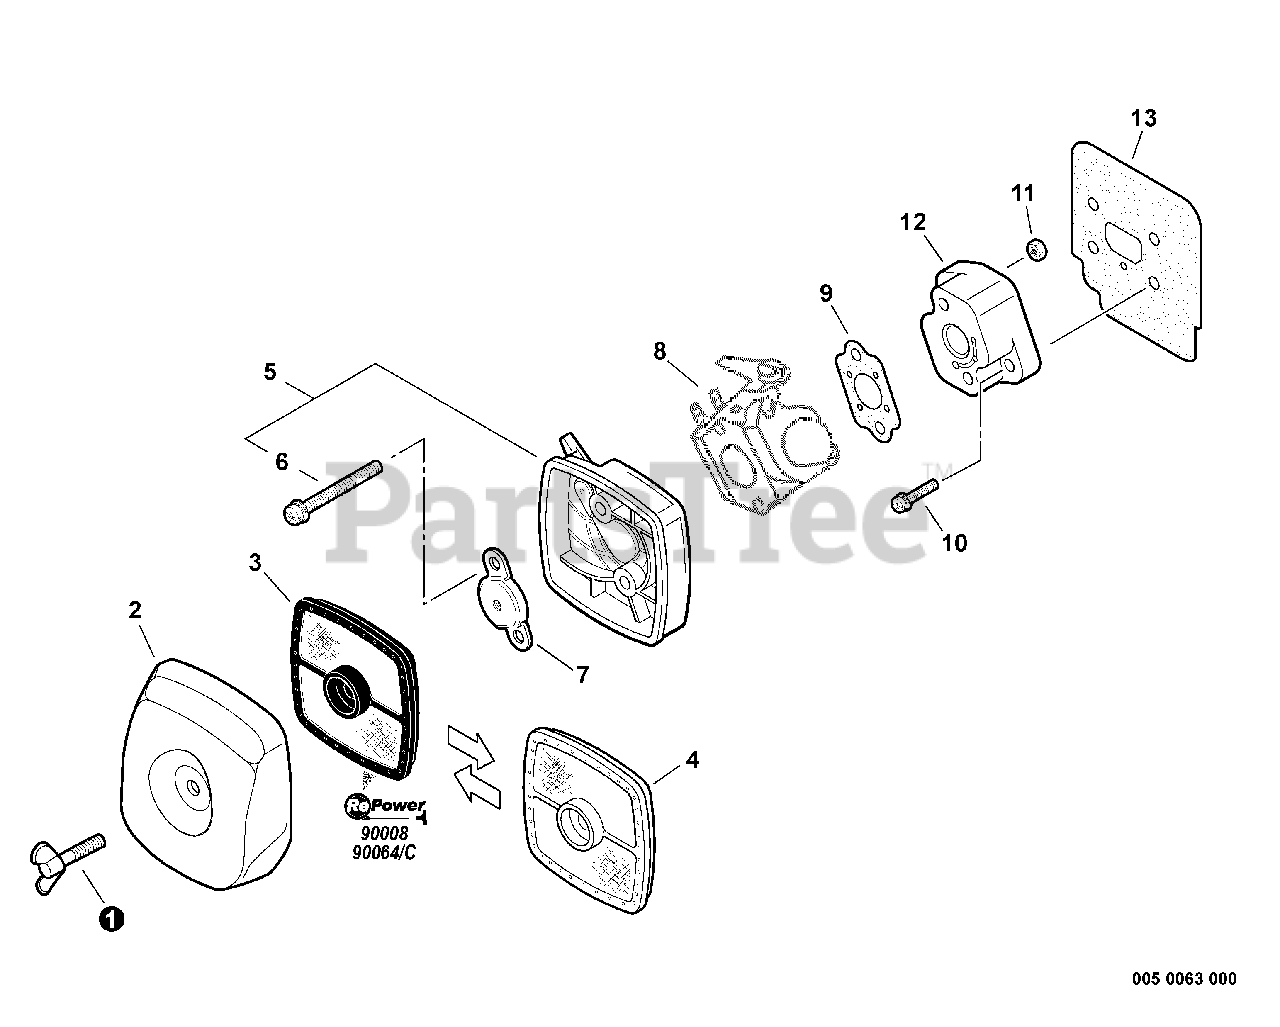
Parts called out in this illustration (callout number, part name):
1	THUMBSCREW
2	COVER, AIR FILTER - GRAY
2	COVER, AIR FILTER - BLACK
3	FILTER, AIR - DOUBLE LAYER
4	FILTER, AIR - SINGLE LAYER
5	AIR FILTER CASE KIT - GRAY
5	AIR FILTER CASE KIT - BLACK
6	SCREW - 5X65
7	PLATE, PREVENT
8	CARBURETOR
9	GASKET, INTAKE
9	RePower TUNE-UP KIT
10	SCREW - 5X20
11	INSULATOR, INTAKE
13	GASKET, INTAKE
14	RePower FILTER KIT
15	RePower TUNE-UP KIT
